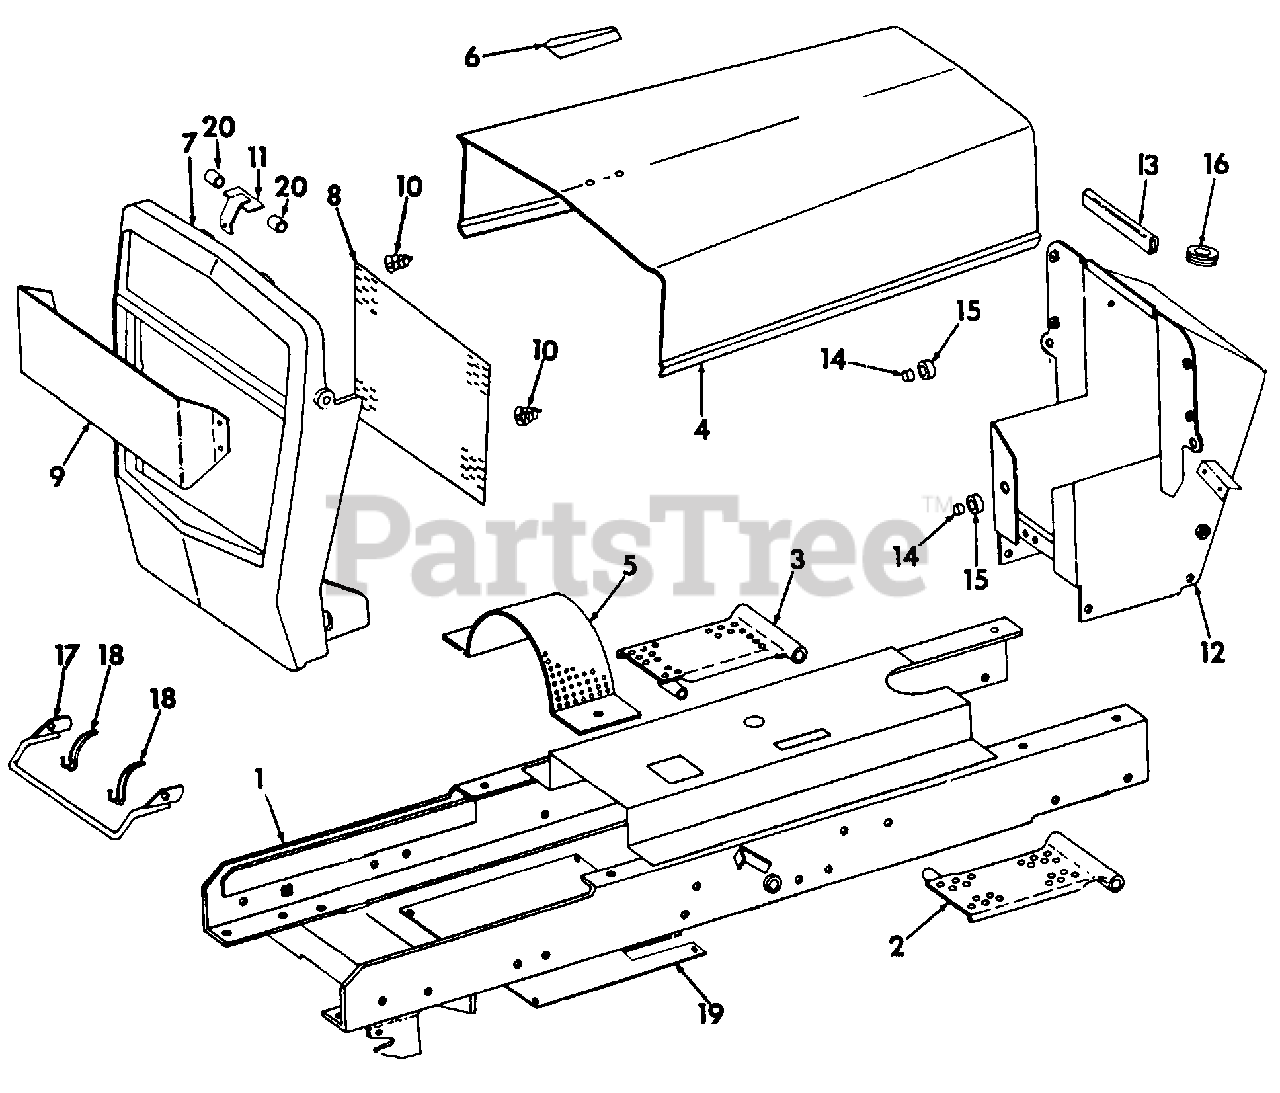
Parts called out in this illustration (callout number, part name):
1	Frame Assy
2	Support Assy, Foot LH
3	Support Assy, Foot RH
4	Hood Assy
5	Shield, Clutch
6	Product Graphic, Hood Ornament
7	Housing, Grille
9	Strip Assy, Grille Panel
10	Spring, Hold Down
11	Bracket Assy, Front Hood
12	Pedestal Assy
13	Bumper, Hood
14	Spacer, Hood Roller Lock
15	Roller, Hood Lock, Rubber Screw, 1/4-20 X 1-1/4 C-Z Hex Hd Cap
16	Grommet, Instrument Panel
17	Hitch Assy, Quick
18	Spring, Latch
19	Sheet, Bottom Clutch Shield
20	Pad, Hood Bumper
